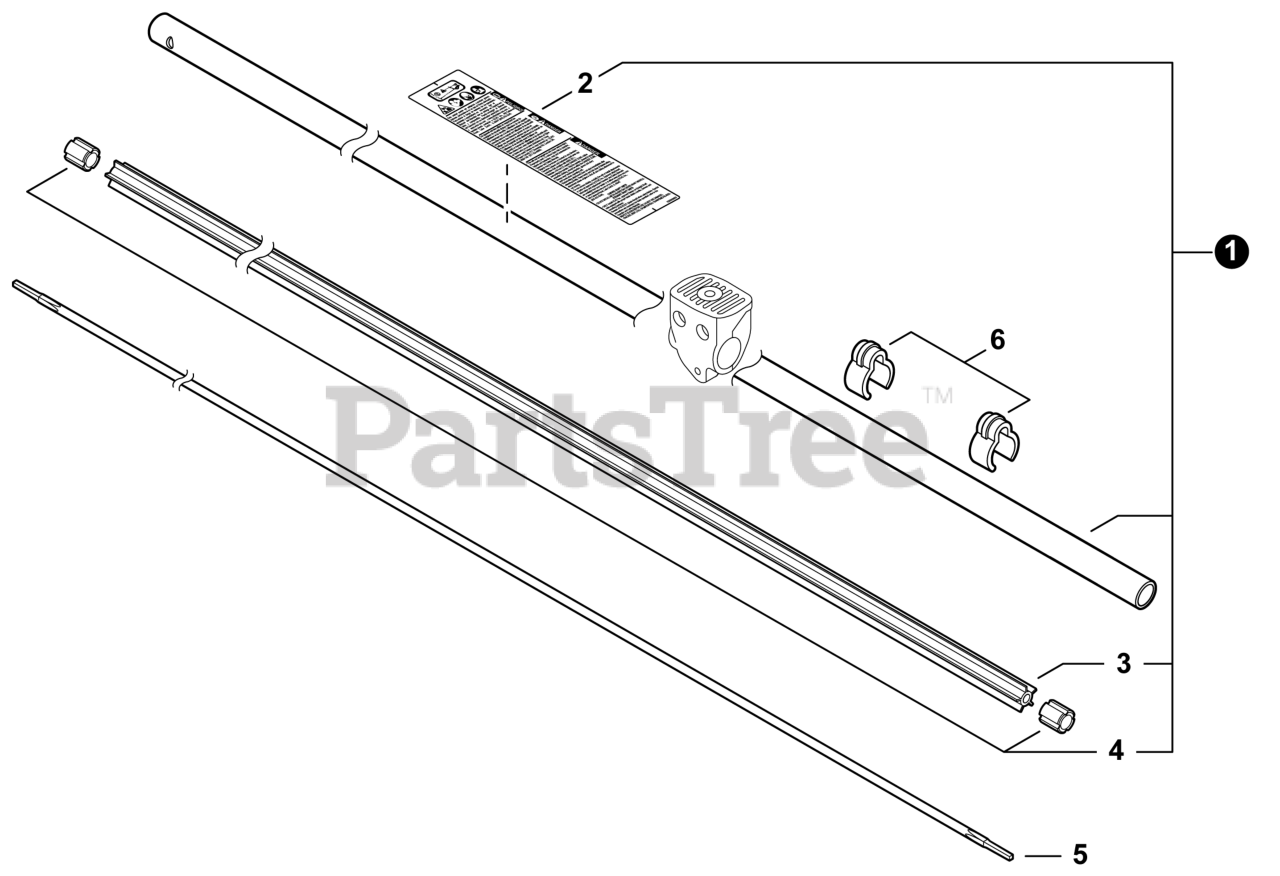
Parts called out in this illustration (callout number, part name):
1	MAIN PIPE ASSY
2	LABEL - CAUTION
3	LINER, FLEXIBLE 21.6x1420
5	DRIVESHAFT - FLEXIBLE
6	CLIP, CABLE 25 MM
